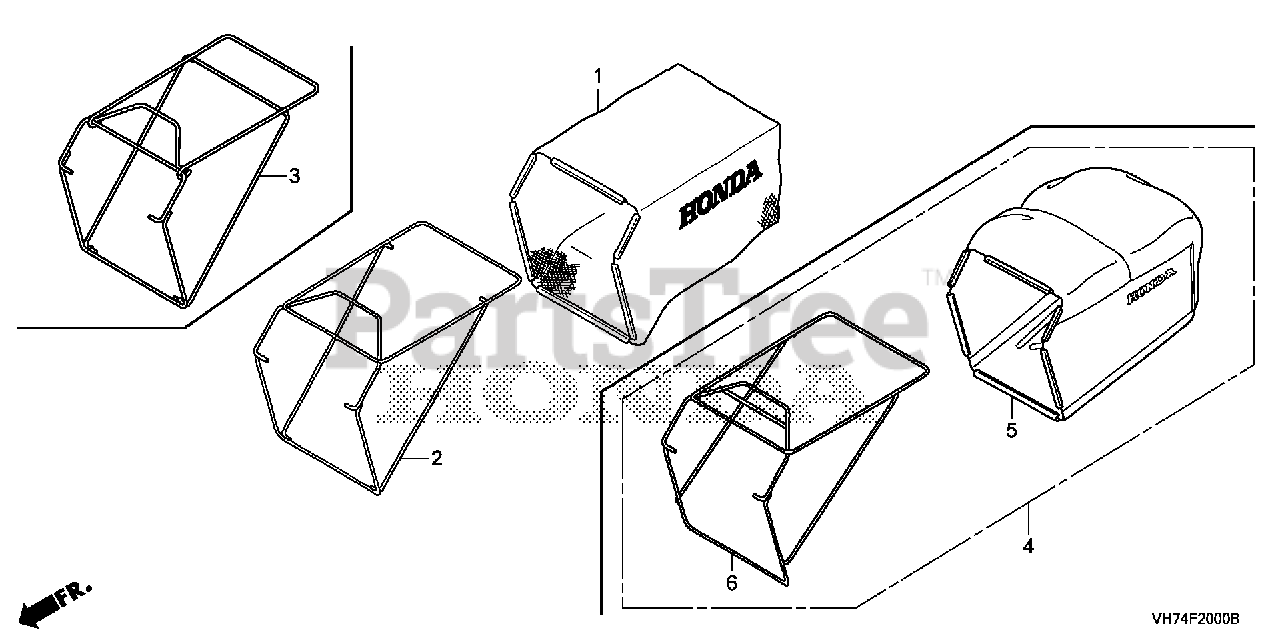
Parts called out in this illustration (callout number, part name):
1	FABRIC, GRASS BAG
3	FRAME, BAG
4	BAG KIT, GRASS
5	FABRIC, GRASS BAG
6	FRAME, BAG
